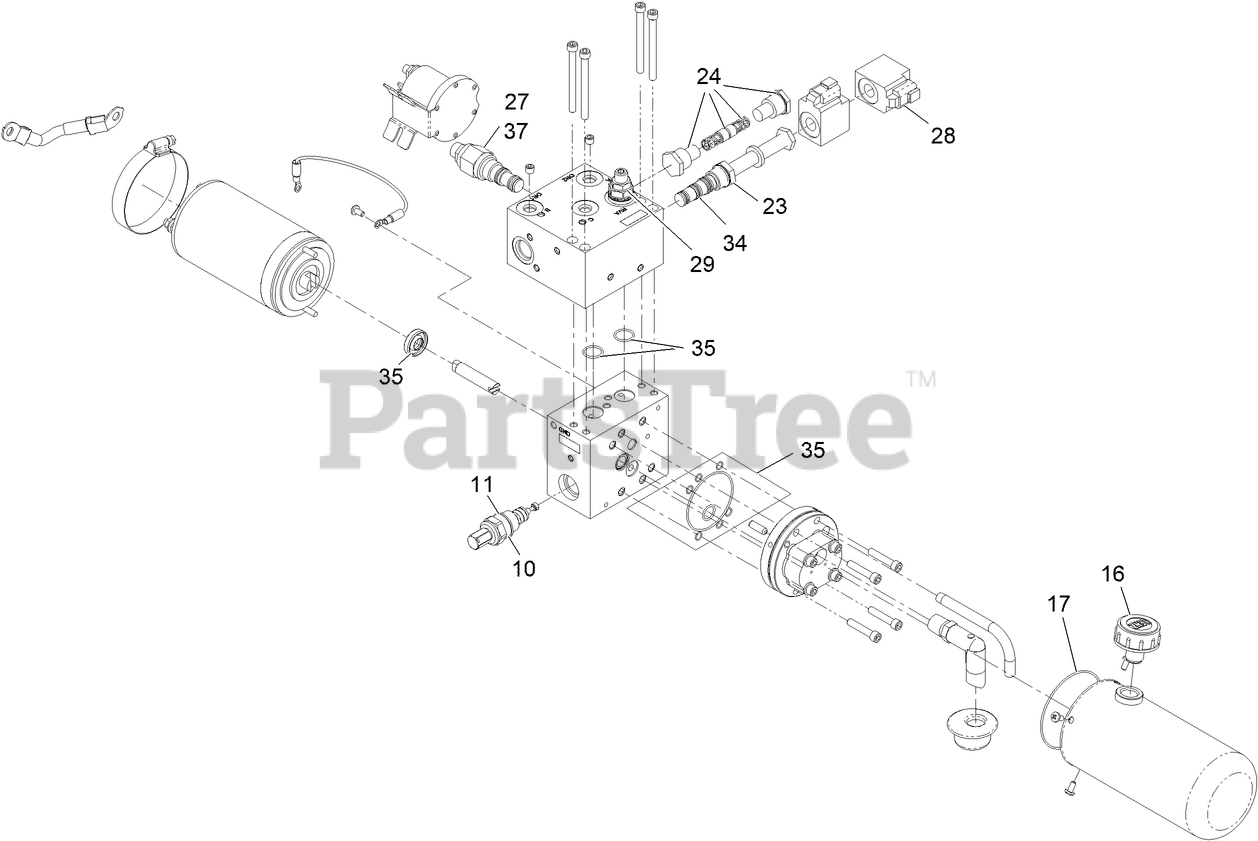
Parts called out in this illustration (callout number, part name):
10	Valve,Relief,Vm01,210-320 Bar
11	Seal Kit
16	CAP-POWERUNIT
23	Cartridge, 4W/3P, 3000PSI, Mc, #8
24	PARTS KIT,DBL PO CK VLV,4INMAN
27	COUNTERBALANCE, 08, 5000-PSI
28	Coil, 12Vdc, 16W, Rect, Deutsch
29	Valve-Relief [1500 Psi]
34	Parts Kit, Seal, 4W/3P Valve
35	Seal Kit
37	Seal Kit
